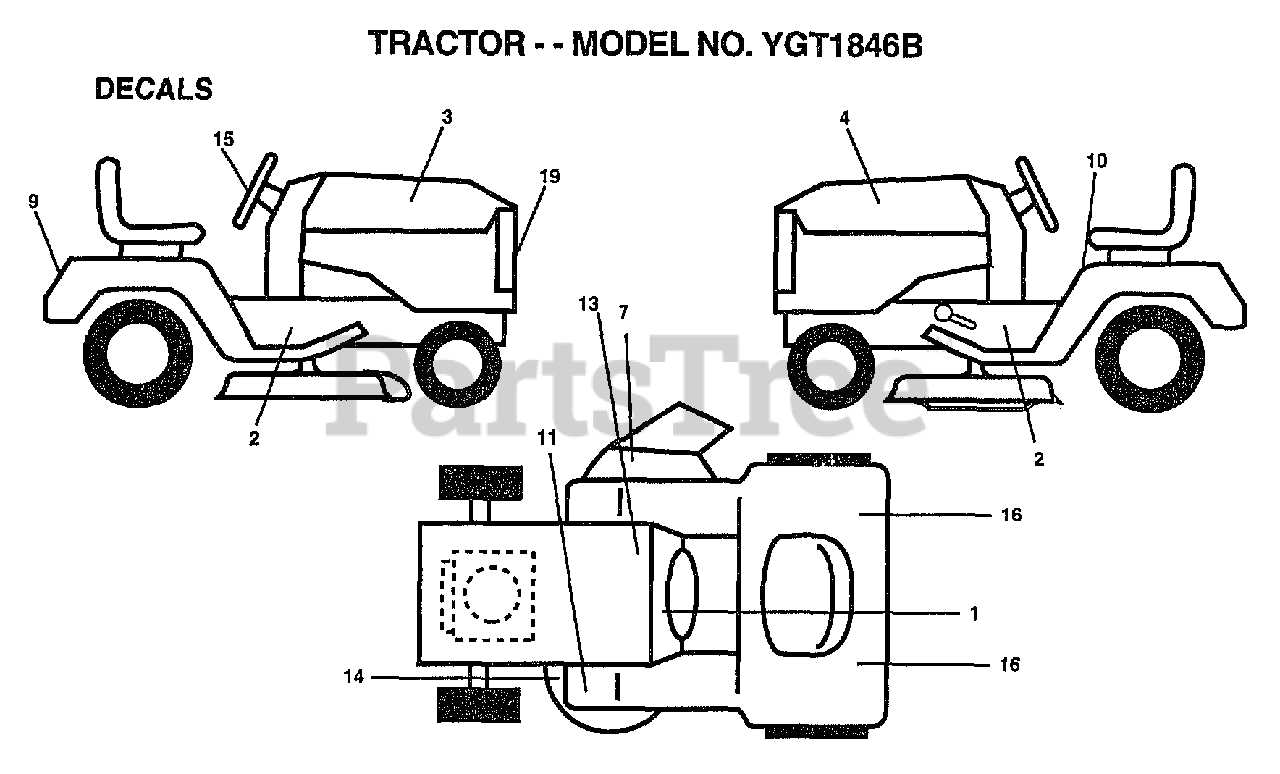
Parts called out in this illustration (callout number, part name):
1	DECAL.INSTR.FRENC
2	"DECAL CHASSIS,46"""
3	"DECAL HOOD,RH,18H"
4	"DECAL-HOOD,LH,18H"
7	"DECAL, WARNING"
9	DECAL FENDER
10	DECAL.CAUT.ENG/FR
11	DECAL T
13	DECAL.BATRY.3-3908
15	DECAL INS STRG WH
16	REFLECTOR-TAIL YT
19	DECAL GRILLE
